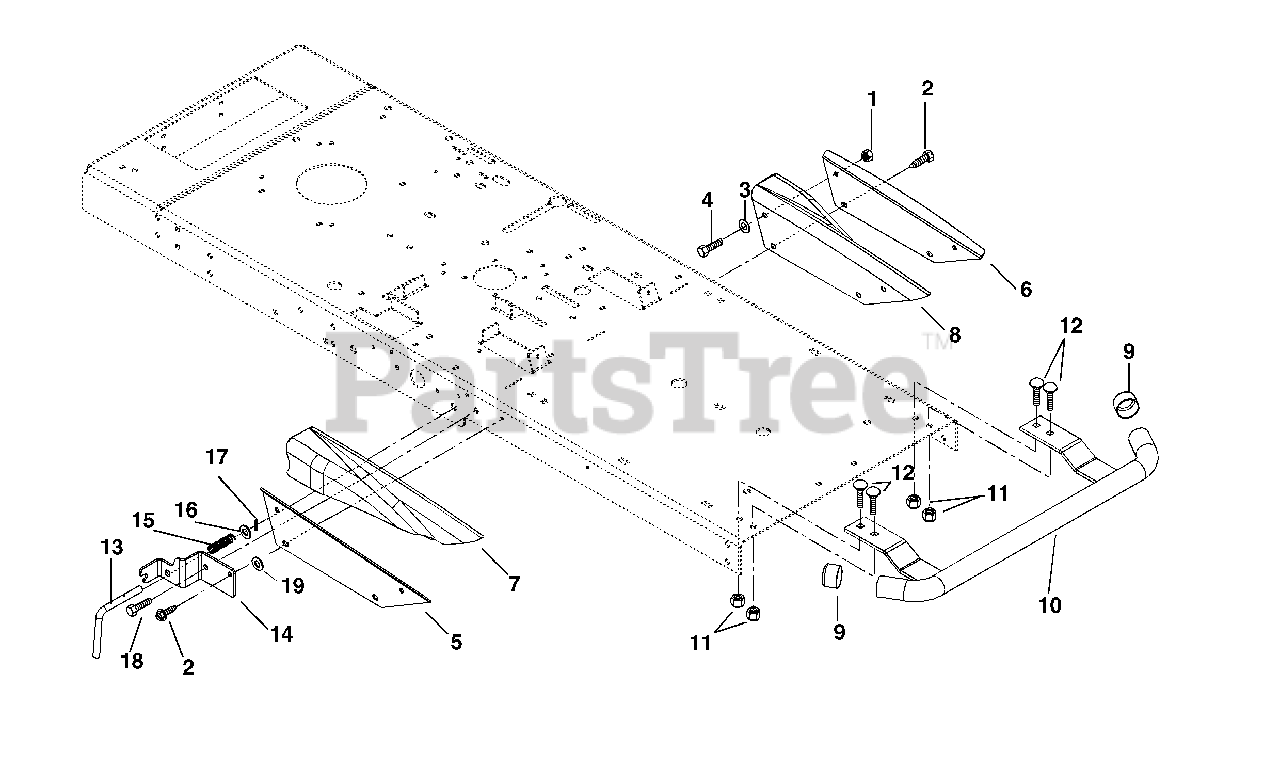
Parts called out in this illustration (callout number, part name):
1	@NUT-LK-NYL .312-18 YWZC
2	@SCR-TAP .31-18X.75 HWH TR YWZ
3	@WSHR-FL-STL.344X.688X.065YWZC
4	@BLT-HEX .31-18X.75 GR5 YWZC
5	BRACKET, RAIL SUPPORT RH
6	BRACKET, RAIL SUPPORT LH
7	RAIL, SIDE RH
8	RAIL, SIDE LH
9	SLEEVE CAP
10	BUMPER, WLDM'T
11	@NUT-LK-NYL .38-16 YWZC
12	@BLT-RDHDSQNK .38-16X1.00 G5YZ
13	PIN-INDEX
14	BRACKET-STOP
15	SPRG, COMP .058X.65X2.13 WLD15
16	@WSHR-FL-STL.531X1.06X.095YWZC
17	PIN-ROLL .156X1.00
18	@BLT-HEX .38-16X1.00 GR5 YWZC
19	WSHR-FL-STL .406X1.00X.188 YWZ
